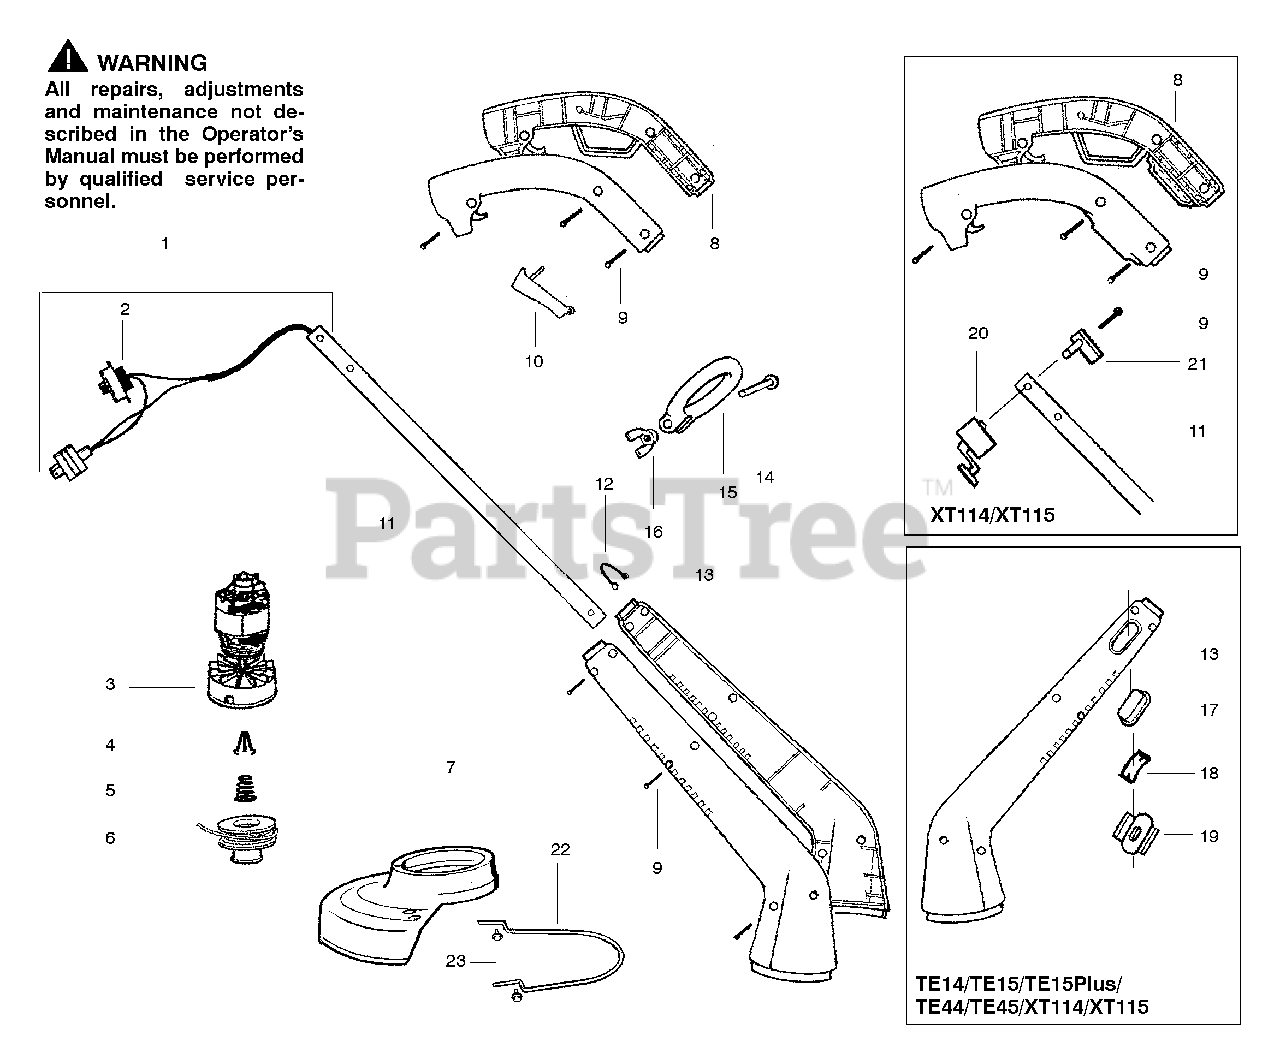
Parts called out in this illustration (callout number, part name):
1	Wiring Harness
2	On/Off Switch
3	Motor/Hub Ass'y.
4	Retainer-Spool
5	Spring-Return
6	Spool w/ Line
7	Shield w/Limiter SG14/TE14/TE44
7	Shield w/Limiter SG15/TE15/TE15Plus/TE45
7	Shield w/Limiter XT114
7	Shield w/Limiter XT115
8	Handle Set SG14/SG15/TE14/TE15/TE15Plus/TE44/TE45
8	Handle Set XT114/XT115
10	Trigger Switch
11	Tube w/Decal
12	Snap Button
13	Housing Set SG14/SG15
13	Housing Set XT114/XT115
13	Housing Set TE14/TE15/TE15Plus/TE44/TE45
15	Assist Handle SG14/SG15/TE14/TE15/TE15Plus/TE44/TE45
15	Assist Handle XT114/XT115
16	Wing Nut
17	Push Button TE14/TE15/TE15Plus/TE44/TE45/XT114/XT115
18	Spring-Button Return TE14/TE15/TE15Plus/TE44/TE45/XT114/XT115
19	Saddle-Tine TE14/TE15/TE15Plus/TE44/TE45/XT114/XT115
20	Button-Handle XT114/XT115
21	Guide-Tube XT114/XT115
22	Edging Guide TE15Plus
23	Screw TE15Plus
